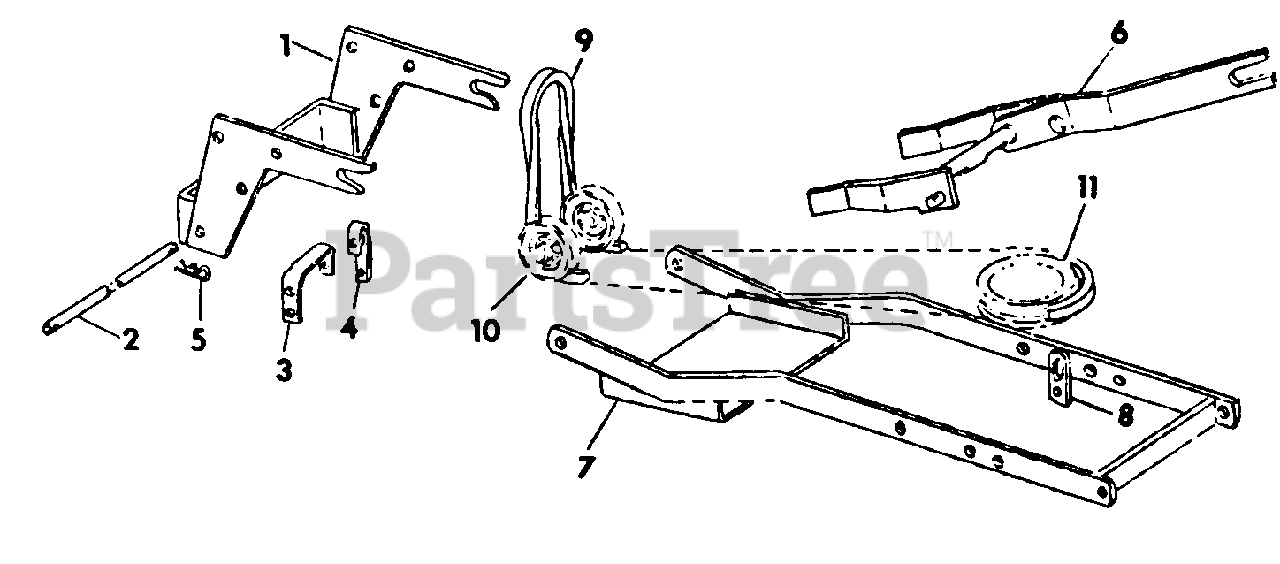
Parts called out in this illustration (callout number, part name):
1	Hanger Assy, Front
2	Rod, Front Mounting
3	Support, Idler LH
4	Support, Idler RH
5	Pin, Quick Attachable Cotter
6	Support Assy, Front Pivot Link
7	Arm Assy, Frame Side
8	Link Assy, Lift
9	Belt, Mule Drive
10	Pulley, Drive Belt Idler -Refer to Hitch
11	Pulley, Center -Refer to Drive Unit
